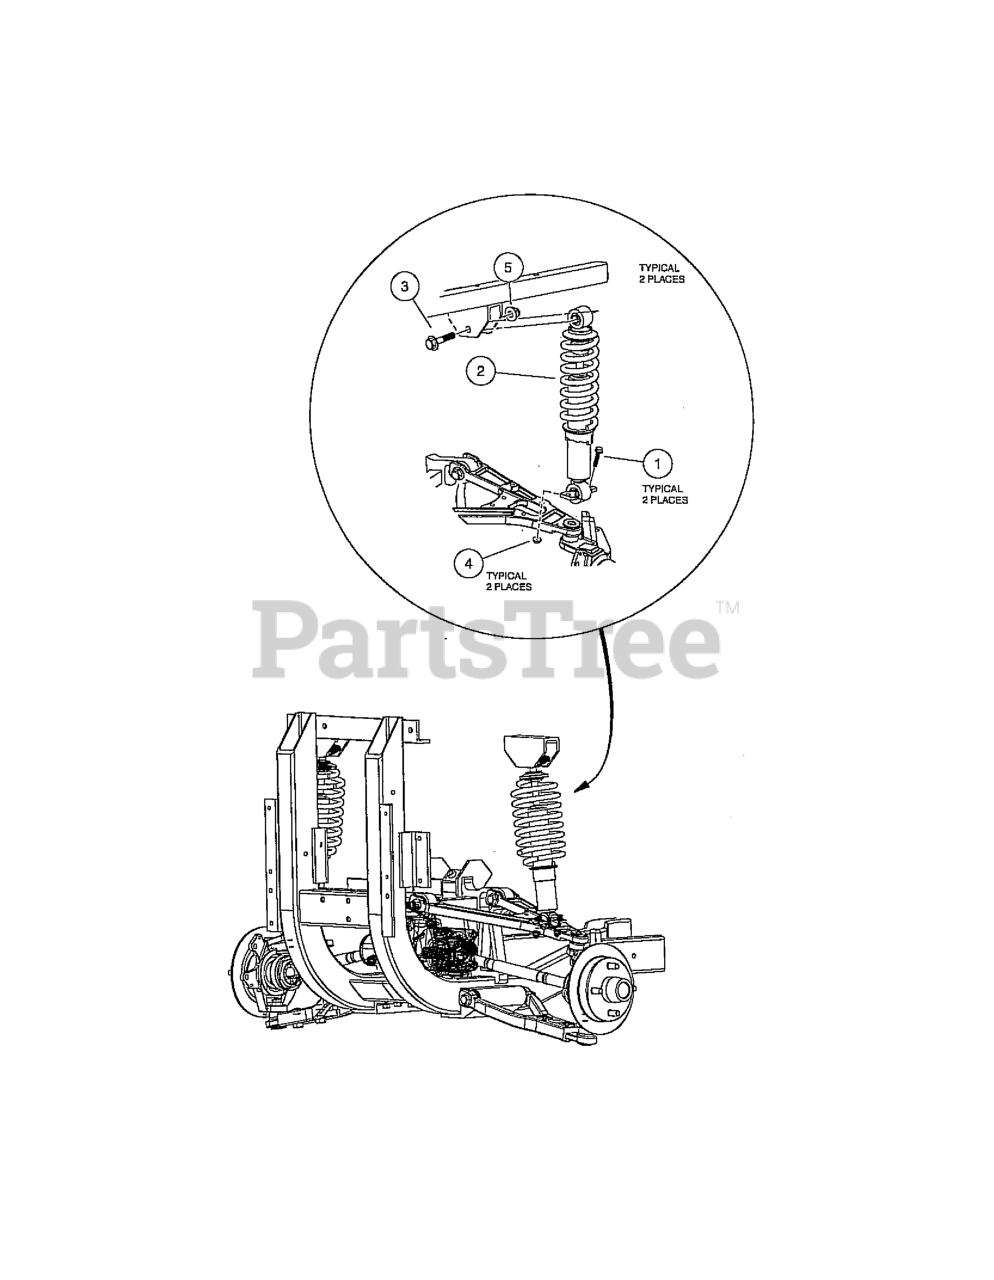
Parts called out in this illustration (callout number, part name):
1	BOLT, FLANGE HD, M8 X 40.0
2	SHOCK, COIL OVER, FRONT
3	BOLT, FLG, M12X1.75X70
4	LOCK NUT, FLG M8 X 1.25 NYLON
5	NUT FLG, M12X1.75, NYLON GR 10
